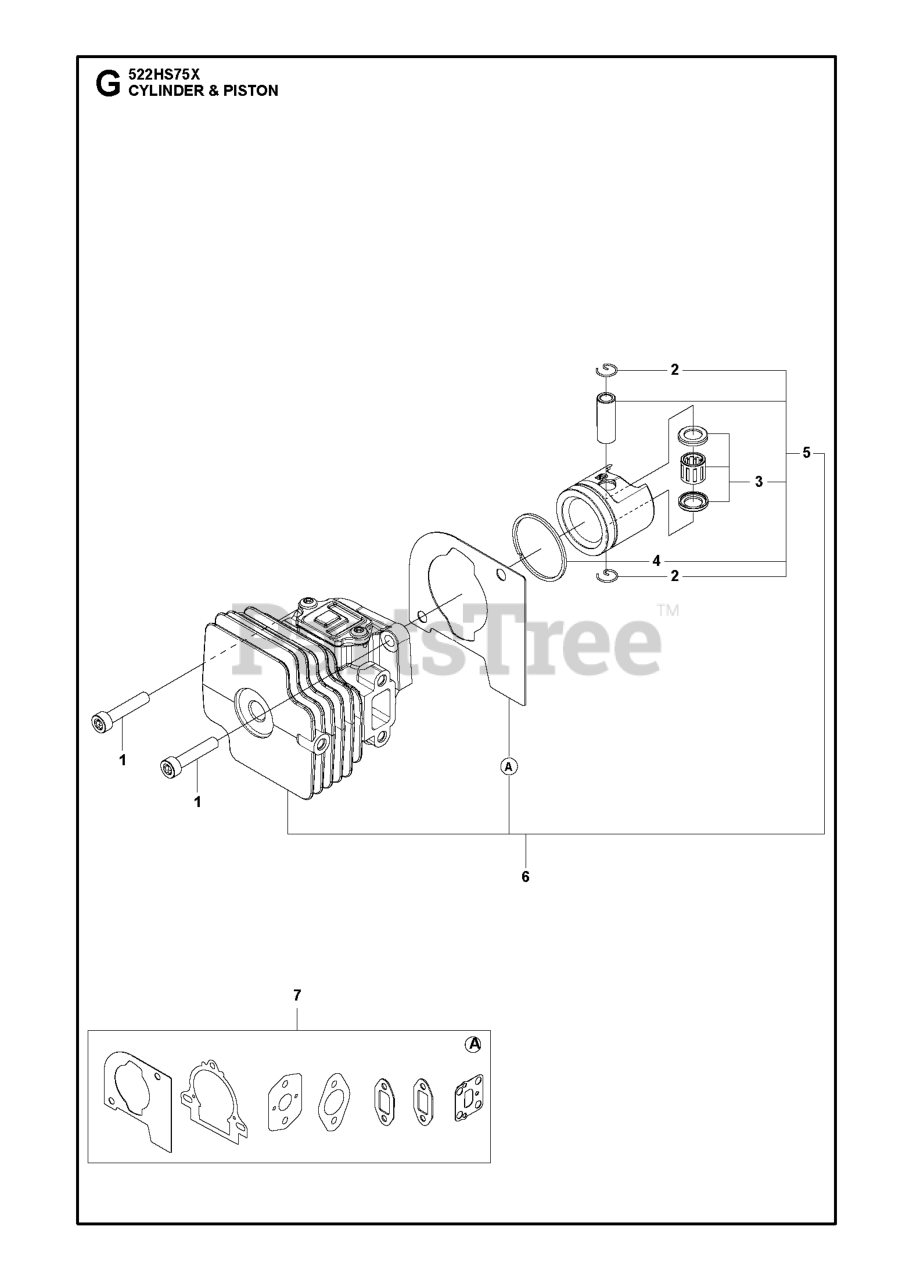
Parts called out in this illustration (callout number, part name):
3	BEARING KIT PISTON PIN
6	CYLINDER ASSY CYLINDER PISTON
7	GASKET KIT 522
